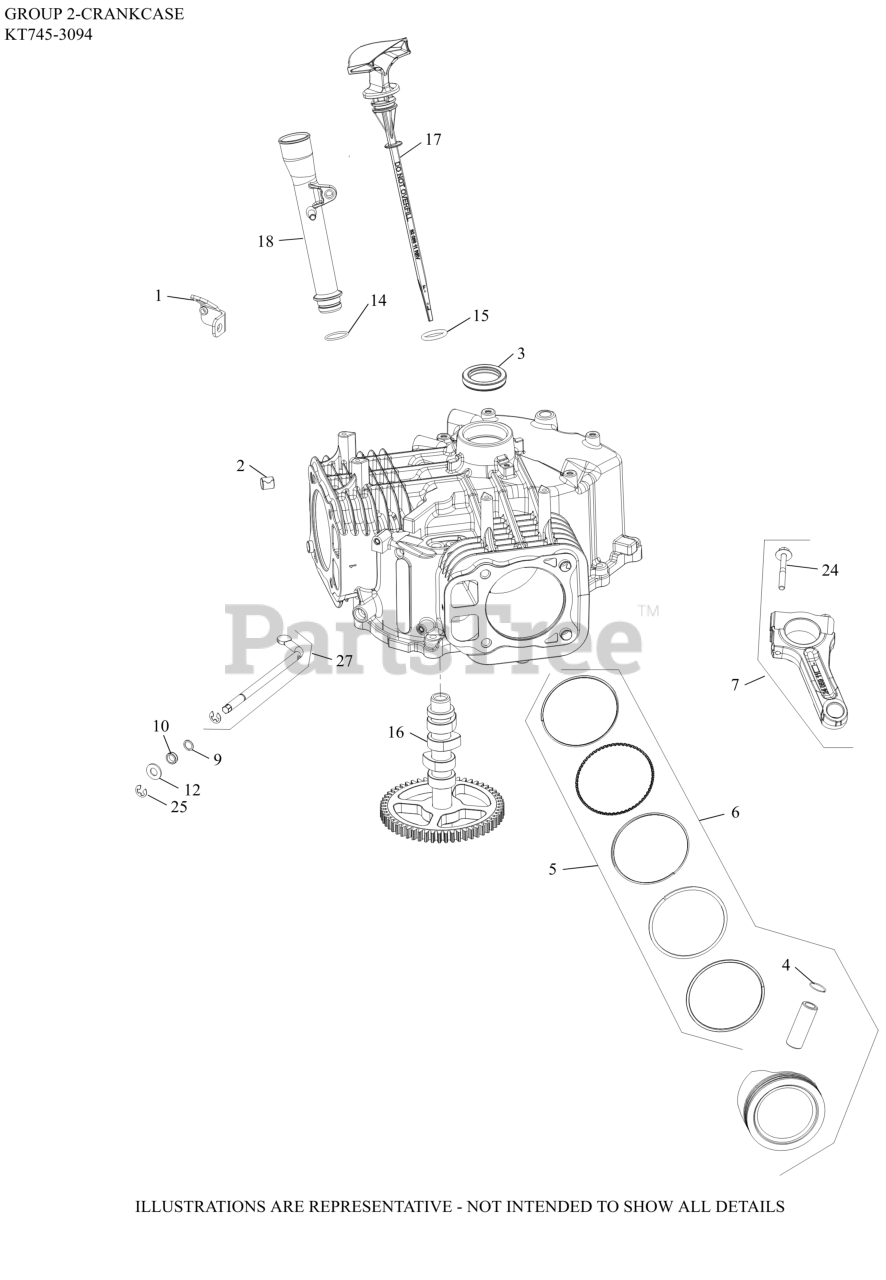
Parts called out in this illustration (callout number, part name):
1	BRACKET, OIL FILL TUBE
2	PIN, LOCATING
3	SEAL, OIL (HELIX LIP)
4	RETAINER, PISTON PIN
5	RING SET(STD)STYLE B-1.2mm Tp RING THICK
5	RING SET(.08)STYLE B-1.2mm RING THICK
5	RING SET(.25)STYLE B-1.2mm Tp RING THICK
5	RING SET(.50)STYLE B-1.2mm Tp RING THICK
6	KIT,PSTN/RNG STYLE B(STD)
6	KIT,PSTN/RNG STYLE B(.08)
6	KIT,PSTN/RNG STYLE B(.25)
6	KIT,PSTN/RNG STYLE B(.50)
7	ROD, ASSEMBLY CONNECTING
9	WASHER, FLAT 11/32"
10	SEAL, GOVERNOR CROSS SHAFT
12	WASHER, FLAT 9 MM
16	CAMSHAFT ASSY
17	DIPSTICK, ASSY
18	TUBE ASSEMBLY, OIL FILL
24	KIT, ROD BOLTS-(#25086677S)
25	CLIP, RETAINER GOVERNOR SHAFT
27	KIT, CROSS SHAFT
